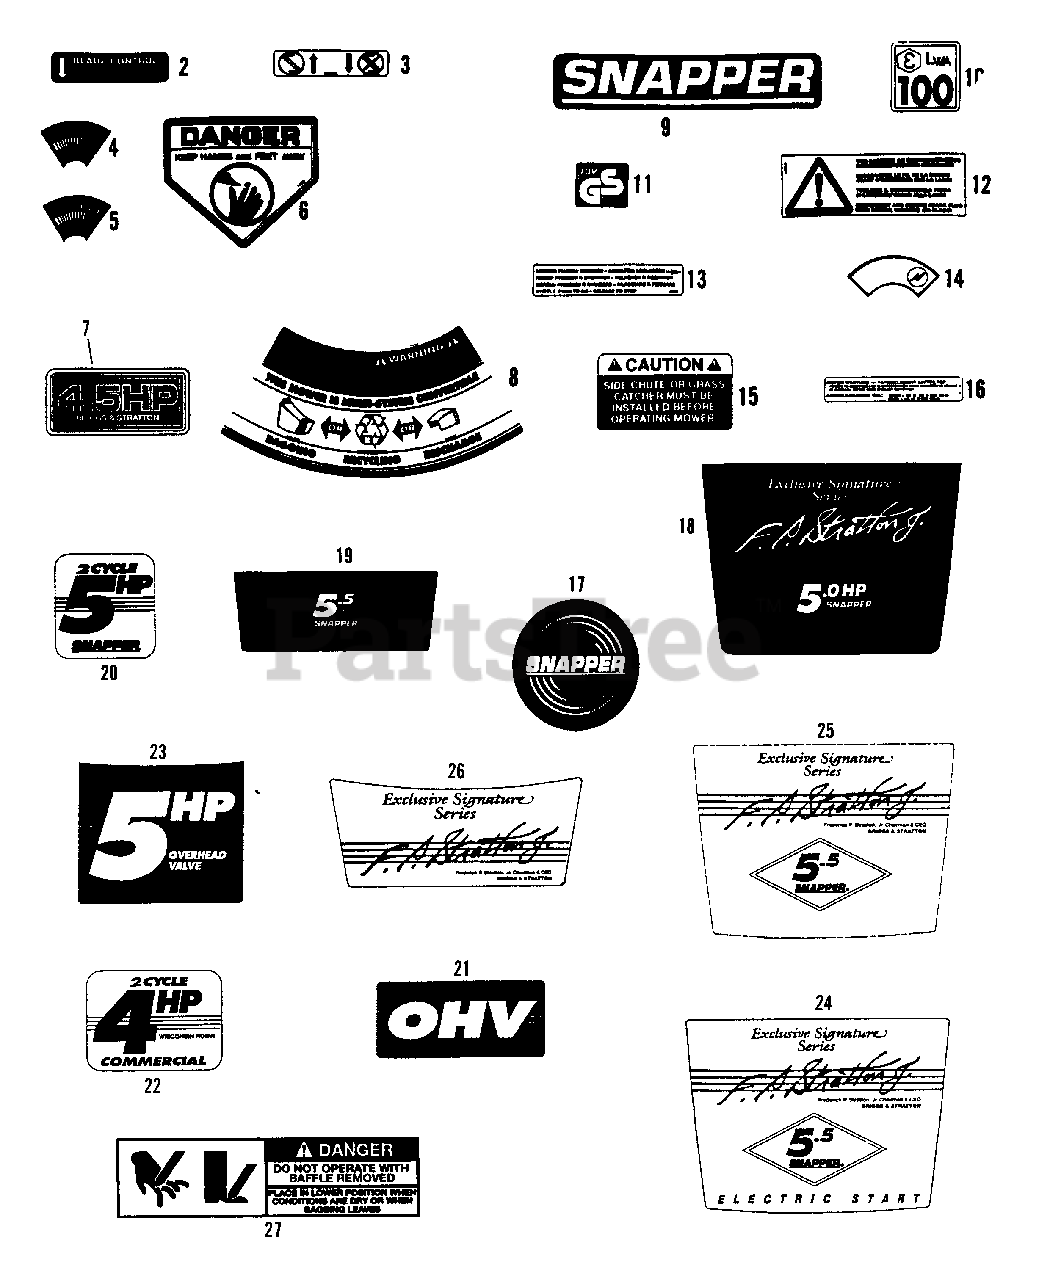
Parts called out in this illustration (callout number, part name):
1	LOGO, Recycling Mulcher (Ninja)
2	DECAL, Blade Control
3	DECAL, Blade Control
4	DECAL, Speed Sector
5	DECAL, Speed Sector
6	DECAL, Danger
7	DECAL, 4.5 HP
8	DECAL, Convertible
9	DECAL, Snapper
10	DECAL, Noise Control
11	DECAL, GS
12	DECAL, Spark Plug
13	DECAL, Wheel Control
14	DECAL, Ignition
15	DECAL, Caution Discharge Opening
16	DECAL, Air Cleaner
17	DECAL, SNAPPER 2.50 Dia.
18	DECAL, 5 HP Signature
19	DECAL, 5.5 HP Overhead Valve
20	DECAL, 5 HP 2 Cycle
21	DECAL, OHV
22	DECAL, 4 HP 2 Cycle
23	DECAL, 5 HP Overhead Valve
24	DECAL, 5.5 HP Signature
25	DECAL, 5.5 HP Signature
26	DECAL, Signature
27	DECAL, Front Baffle
